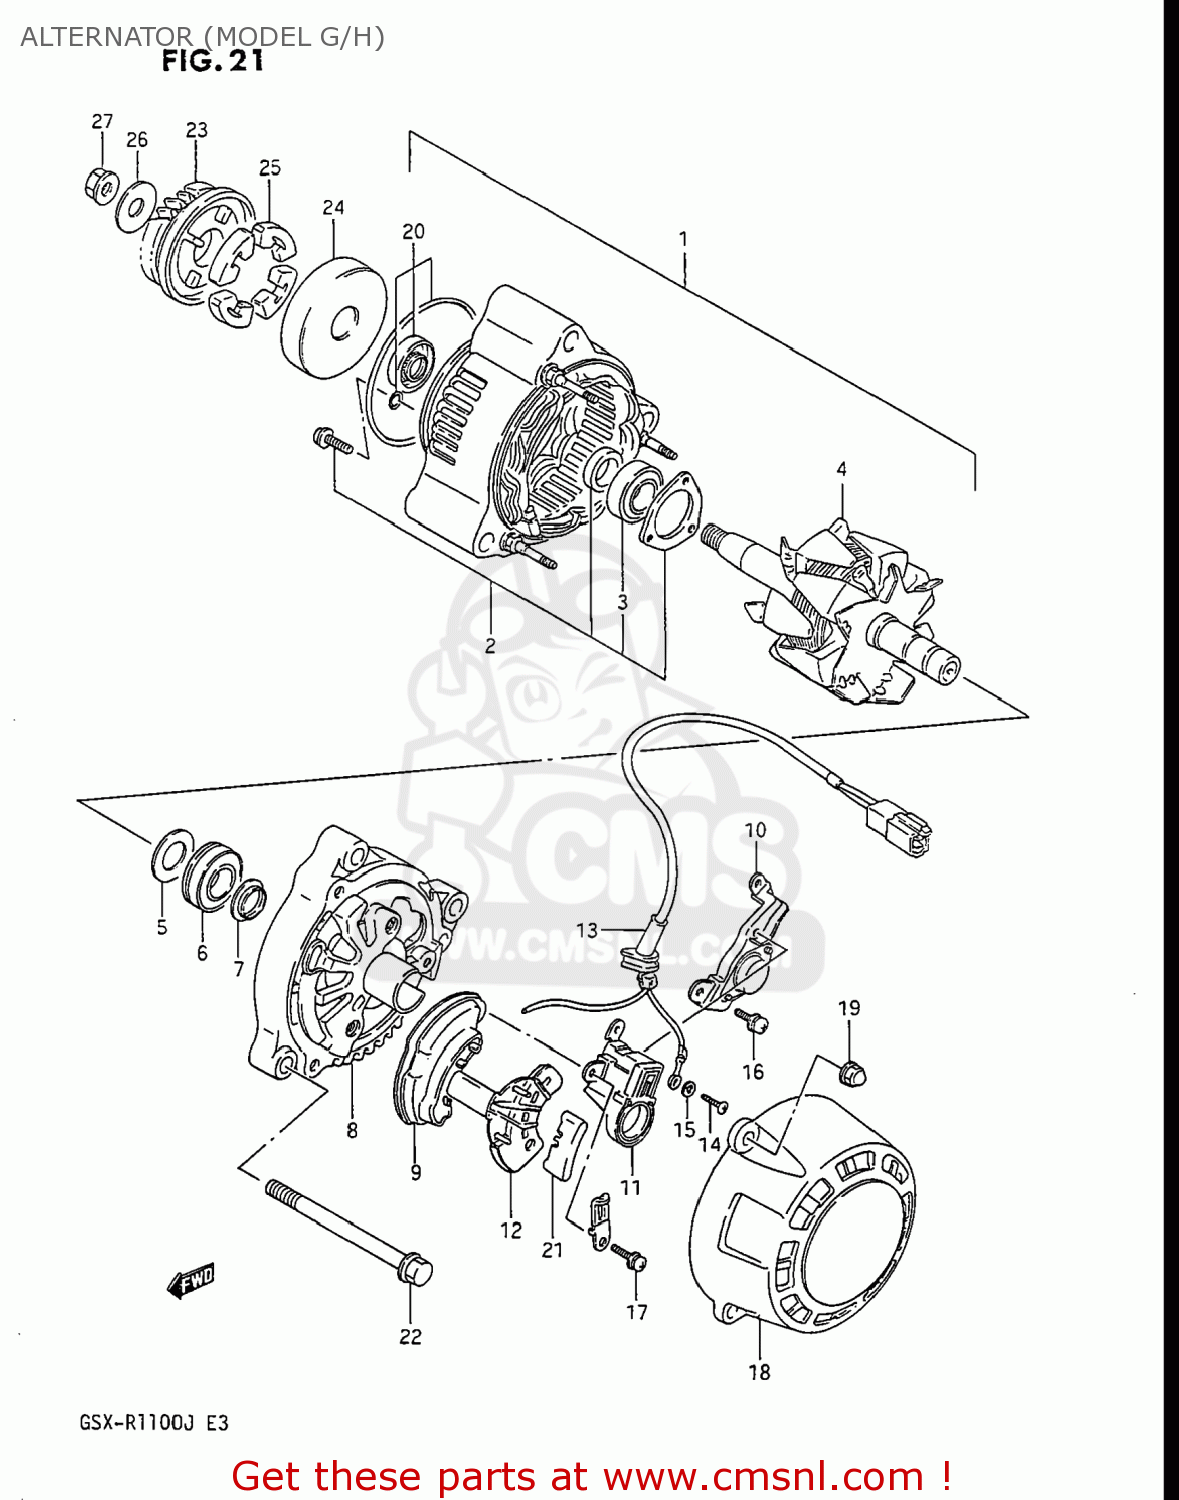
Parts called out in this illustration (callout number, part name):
1	ALTERNATOR ASSEMBLY
2	FRAME,DRIVE END
3	BEARING
4	ROTOR
5	COVER (2)
6	BALL BEARING,ALTERNATOR
7	COVER(2)
8	FRAME,END
9	HOLDER,RECTIFIER
10	REGULATOR
11	HOLDER,BRUSH
12	COVER,RECTIFIER
13	WIRE,LEAD
14	SCREW
15	LOCK WASHER
16	SCREW
17	SCREW
18	COVER
19	NUT
20	OIL SEAL SET
21	BUSH
22	BOLT (8X90)
23	GEAR,GENERATOR DRIVEN
24	HOUSING,GENERATOR GEAR
25	DAMPER,GENERATOR DRIVEN
26	WASHER
27	NUT
